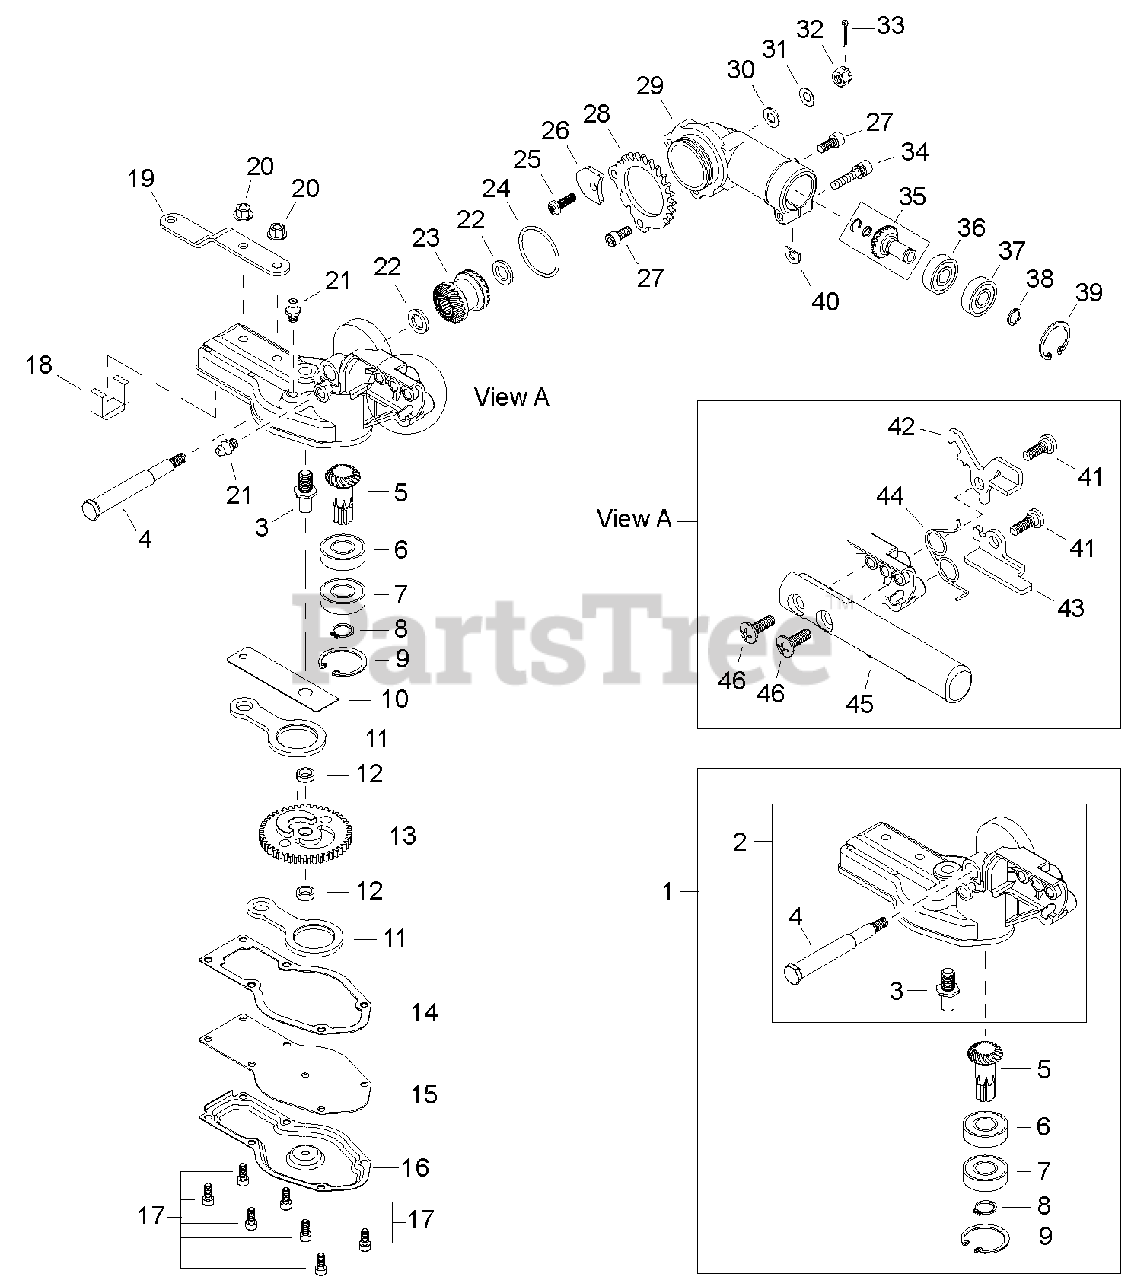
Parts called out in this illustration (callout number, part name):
2	GEAR CASE ASSY
3	PIPE, MAIN
5	PINION SHAFT
6	BEARING, BALL - 6001
7	BEARING, BALL - 6001ZZ
8	RING, RETAINING - 12
9	RING, RETAINING - 28
10	PLATE, GUIDE
11	ROD, CONNECTING
11-1	GEAR CASE ASSY
11-4	SHAFT
12	SPACER
13	CAM GEAR
14	GASKET
15	SPACER
16	GEARCASE COVER
17	SCREW - 4X10
18	SEAL, FELT
19	BRACKET, CUTTER
20	NUT - 5 -- FLANGE
21	FITTING, GREASE
22	COLLAR
23	GEAR - BEVEL
24	O-RING
25	SCREW - 5X16
26	STOPPER PLATE
27	SCREW - 5X12
28	LOCKING RING
29	UPPER GEARCASE HOUSING
30	WASHER - 6
31	WASHER - CONICAL
32	NUT - CASTLE
33	PIN, SPLIT
34	SCREW - 5X25
35	GEAR - BEVEL
36	BEARING, BALL - 609
37	BEARING, BALL - 609ZZ
38	RING, RETAINING
39	RING, RETAINING - 24
40	SHIM
41	SCREW
42	LEVER, LOCK
43	LEVER, LOCK
44	SPRING
45	CUTTER ADJUSTMENT LEVER
46	SCREW - 6X20
